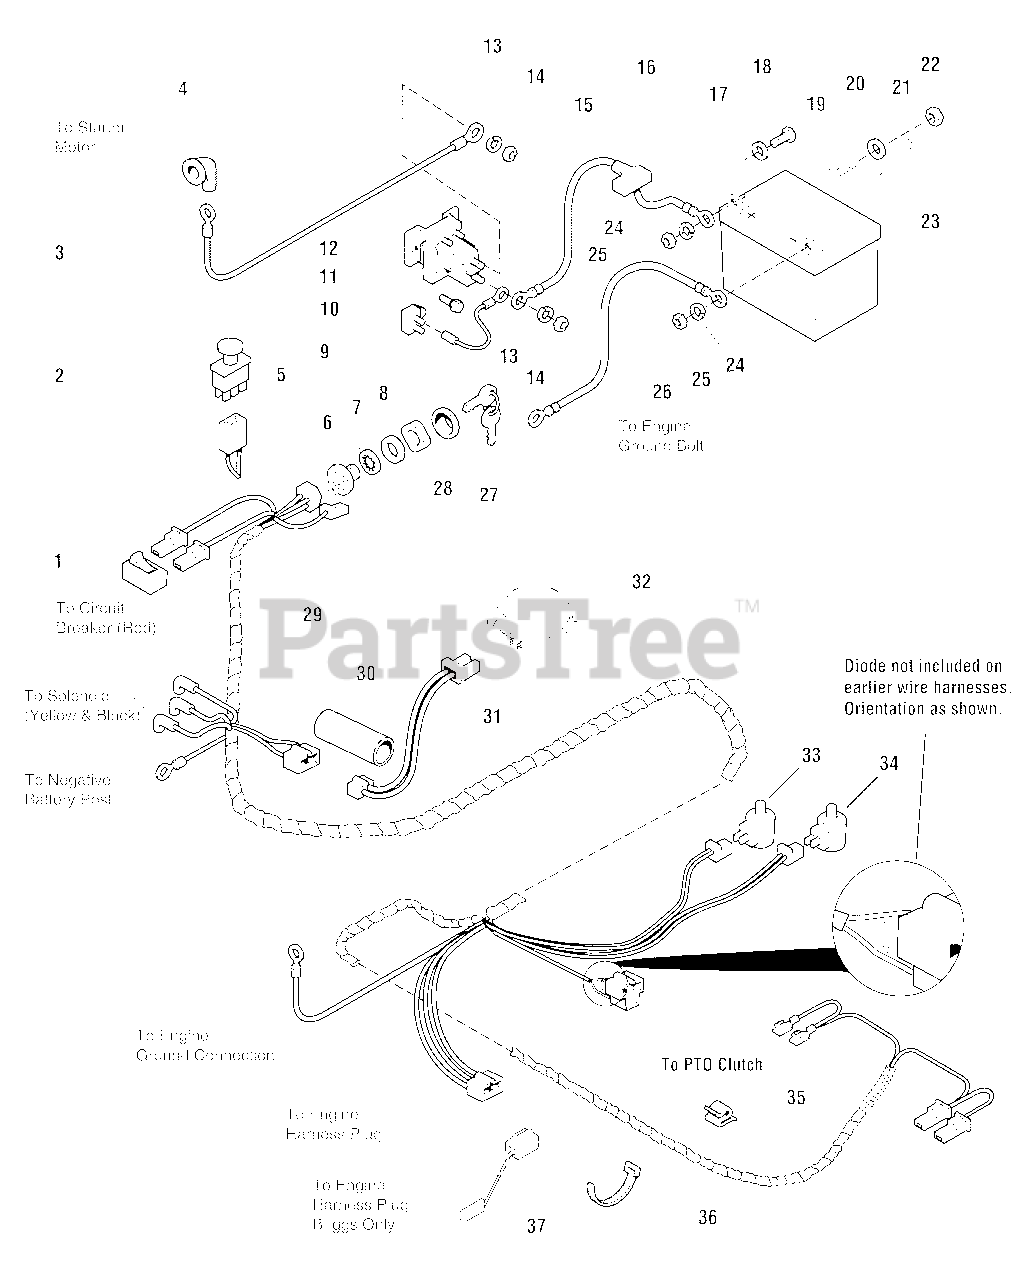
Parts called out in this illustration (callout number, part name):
1	SWITCH, Headlights
2	SWITCH, PTO, Push/Pull
3	CABLE, # 6, 42-1/2" Long
4	COVER, Terminal
5	SWITCH ASSEMBLY, Ignition, 6 Pin (Includes Ref. Nos. 6, 7, 8, 27, & 28)
6	LOCKWASHER, Internal Tooth 5/8
7	WASHER, 5/8
8	NUT, Hex Flange, 5/8-32
9	WIRE, 12GA, 5.9 Long Red
10	BREAKER, Circuit 12Volt, 20Amps w/Tab
11	CAPSCREW, Hex Washer Head Taptite, 1/4 x 5/8
12	SOLENOID, 4 Pole 12 Volt DC
13	LOCKWASHER, External Tooth, 5/16
14	NUT, Hex, 5/16-24 Yellow
15	CABLE, # 6, 10" Long
16	BOOT, Insulator Battery Terminal
17	WASHER, 1/4
18	CAPSCREW, Hex Head, 1/4 x 3/4
19	CAPSCREW, Hex Head, 5/16-18 x 3/4
20	WASHER, 5/16
21	ROD, Battery Hold Down
22	NUT, Hex Lock ESNA, 5/16-18
23	BATTERY, 12 Volt
24	LOCKWASHER, 1/4
25	NUT, Hex, 1/4-20
26	CABLE,# 6, 52-1/2" Long
27	KEYS, Ignition
28	COVER, Ignition Switch
29	WIRE HARNESS
30	SHRINK TUBE
31	WIRE ASSEMBLY, 16GA, 16" Long, Black/Tan
32	SWITCH, Seat, Gray Switch, Gray Retainer
32	SWITCH, Seat, Gray Switch, Black Retainer
33	SWITCH, Push, Black
34	SWITCH, Push, Grey
35	CLIP, Wire
37	WIRE ASSEMBLY
